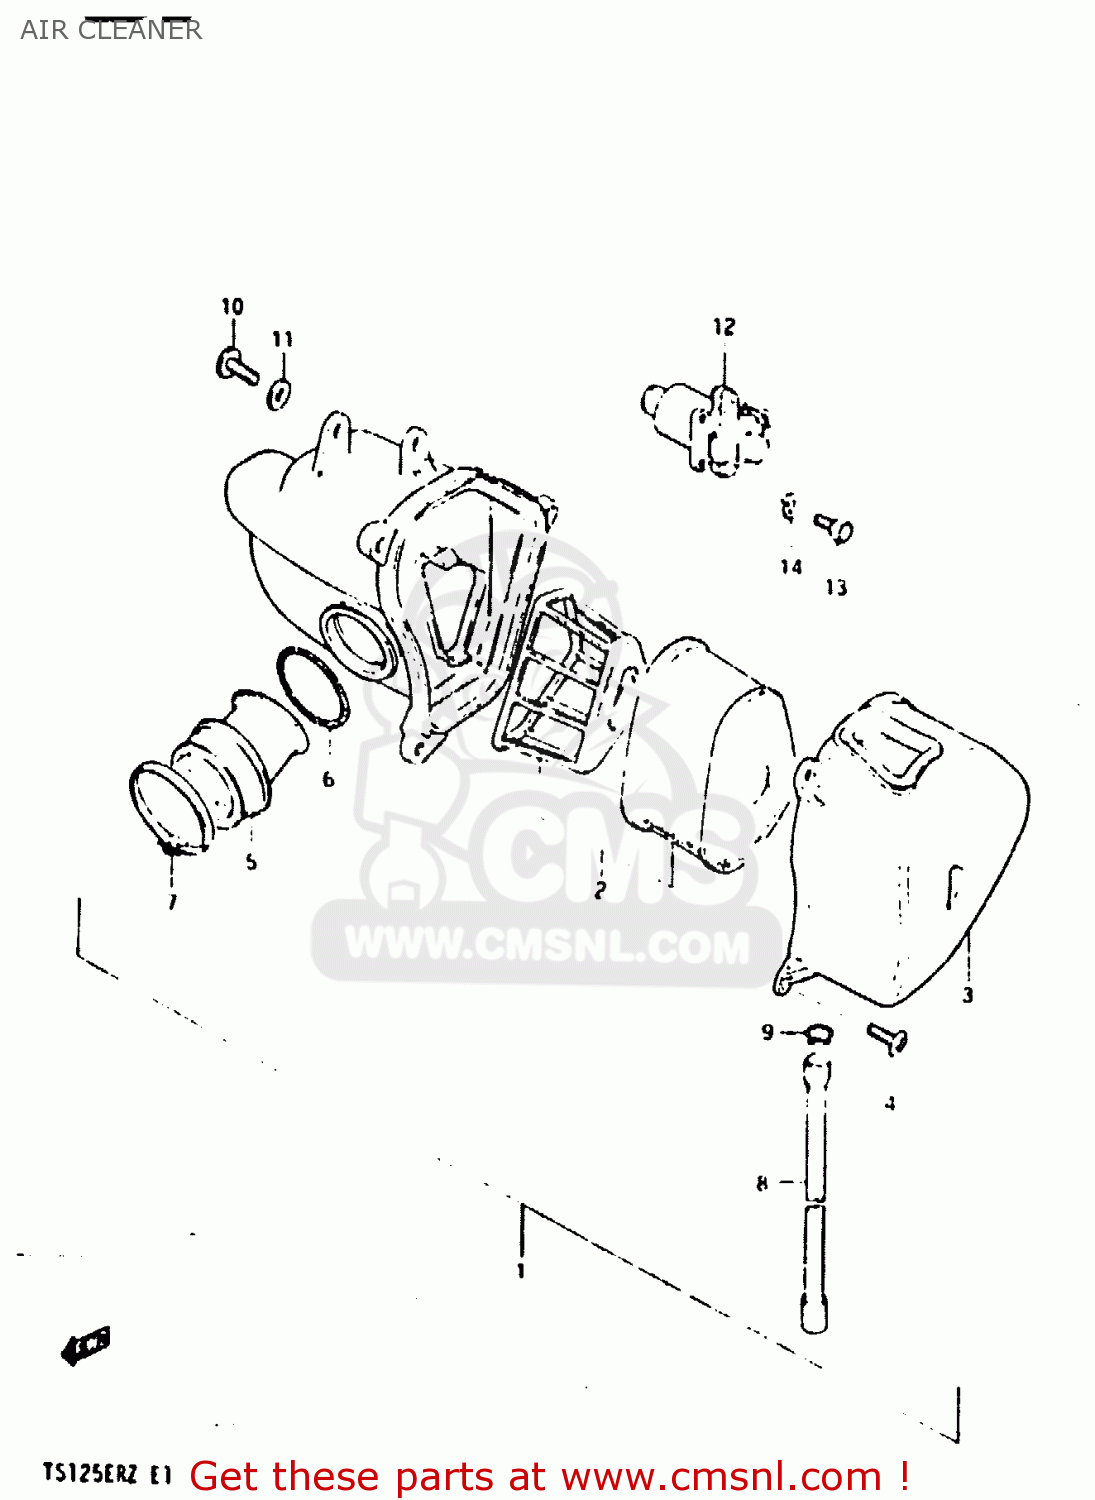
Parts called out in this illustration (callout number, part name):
1	CLEANER ASSY, AIR
2	FILTER ASSY
3	CAP
4	SCREW
5	TUBE,OUTLET
6	SPRING,AIR CLEANER SIDE
7	CLAMP
8	TUBE, DRAIN
9	CLIP
10	SCREW
11	WASHER
